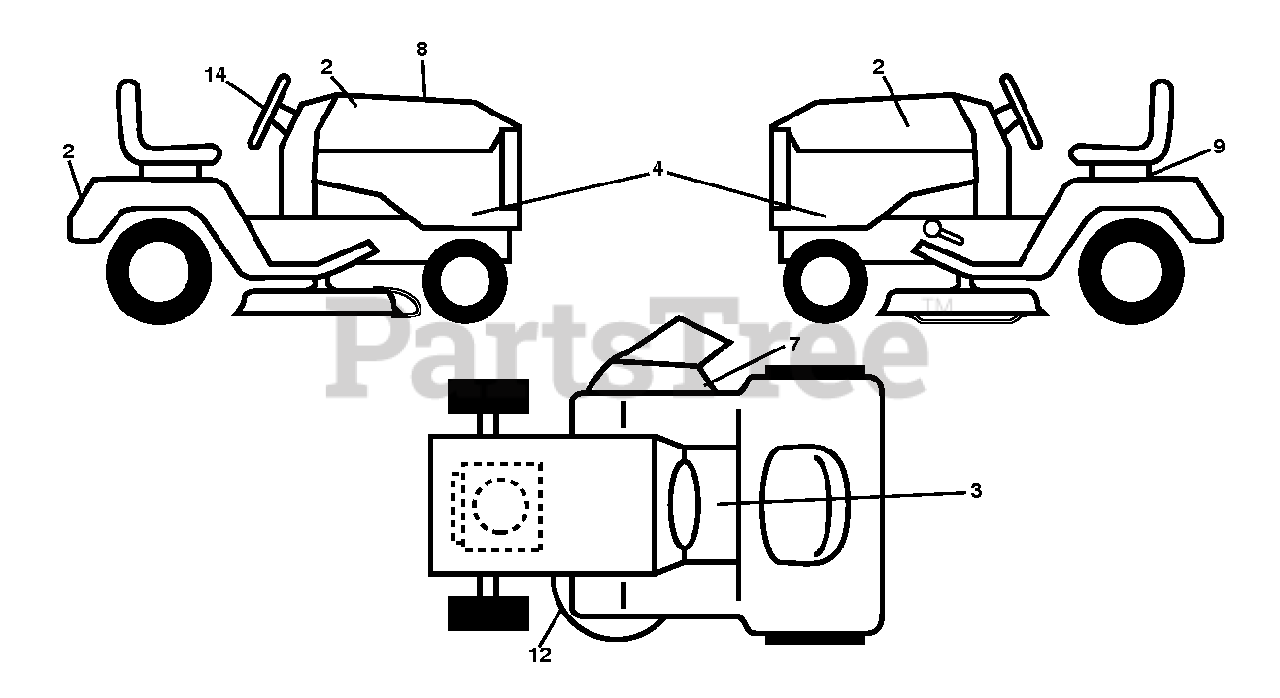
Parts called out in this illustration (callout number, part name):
3	DECAL.WARN.START.INSTRUCTIONS
7	DECAL.WARN.KEEP.HAND.AWAY
9	DECAL BTRY SYMBOLS
12	DECAL V BELT SCHEMATIC
